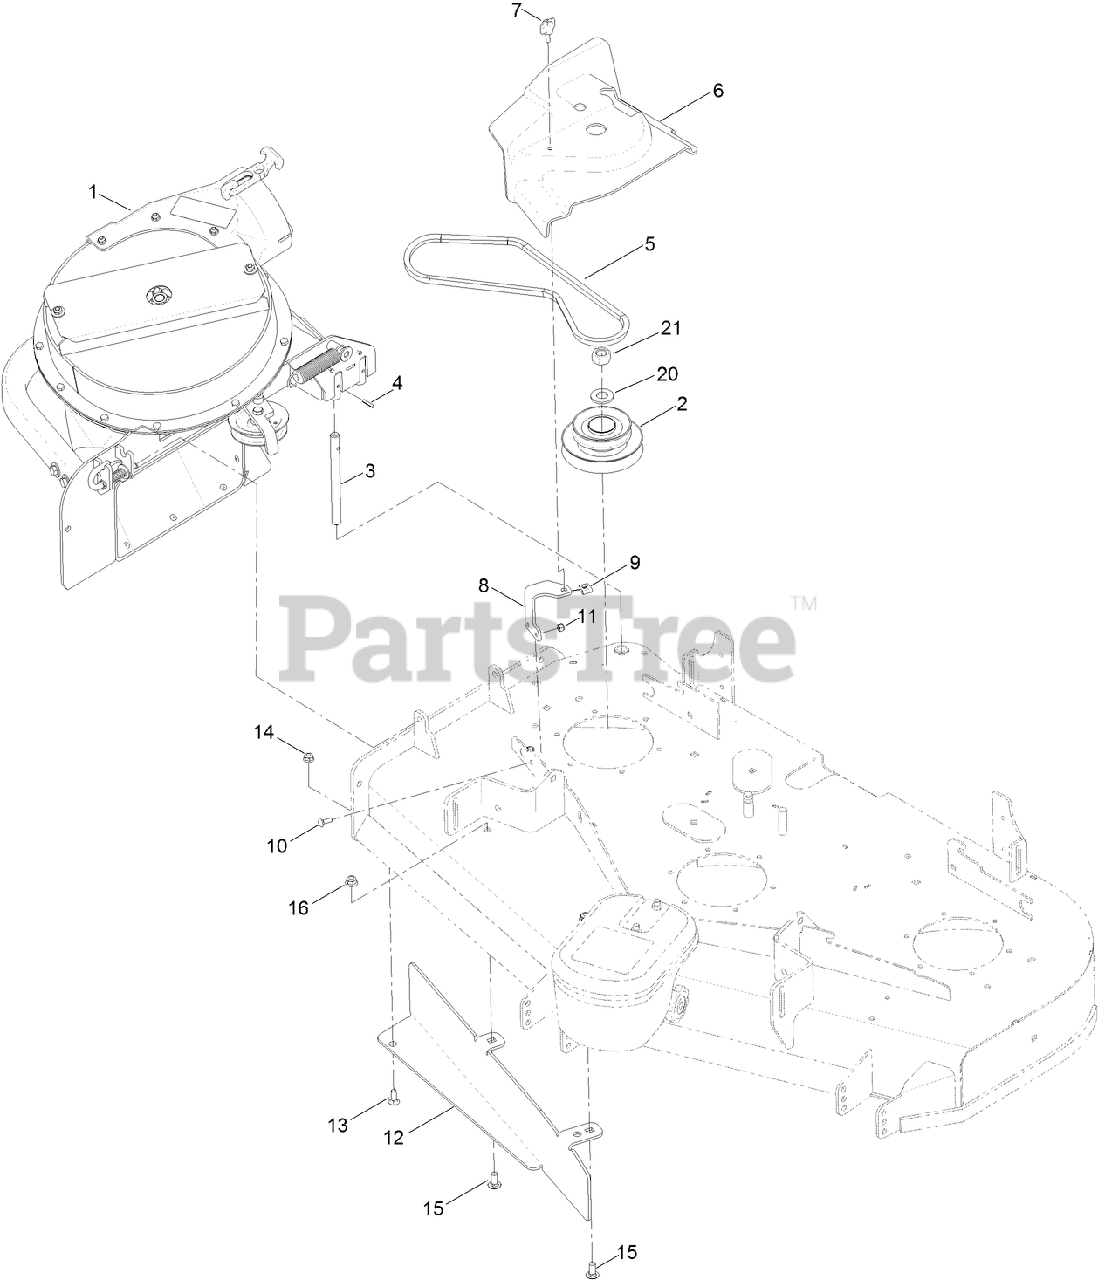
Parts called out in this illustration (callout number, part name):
1	BLOWER ASM
2	DRIVE-JACKSHAFT
3	SHAFT-CATCHER, GRASS
4	PIN-ROLL
5	BELT-V
6	BELT-COVER
8	BRACKET-COVER, BELT
9	NUT-SPEED
10	BOLT-CARR
11	NUT-LOCK, NI
12	BAFFLE-BAGGER
13	SCREW-CARR
14	NUT-HF, NI
15	SCREW-CARR
16	NUT-HF, NI
20	WASHER
21	NUT-HEX
